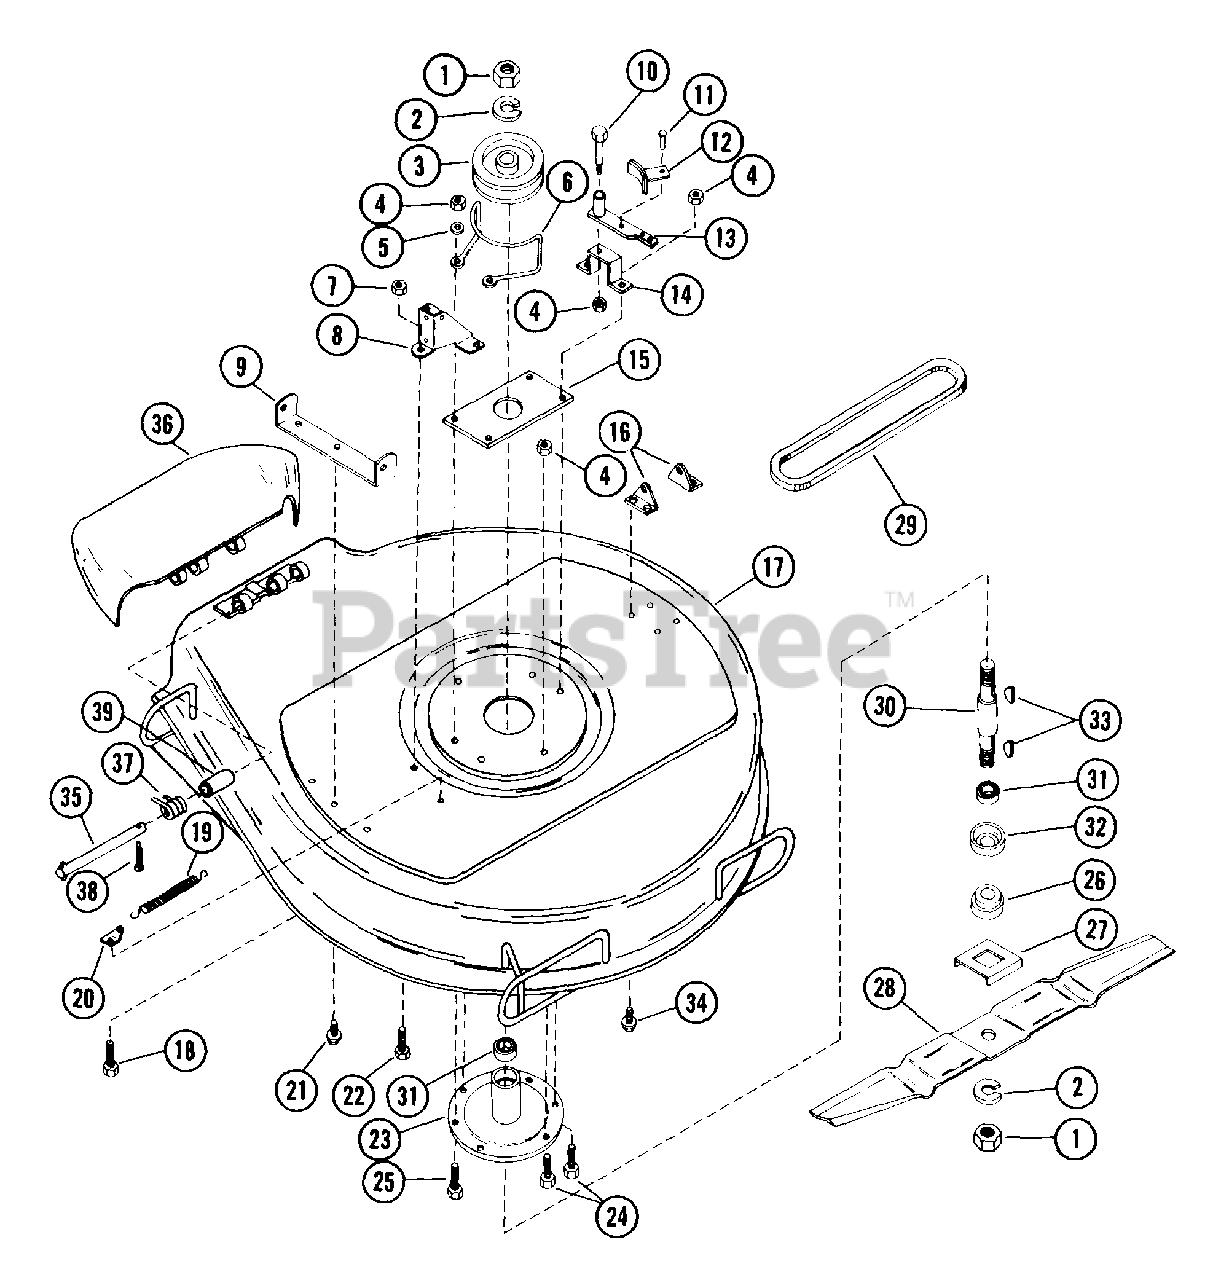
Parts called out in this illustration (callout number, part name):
1	NUT-JAM .75-10 PL
2	WSHR-LK .750X.188 MED PL
3	MOWER SHEAVE
4	NUT-LK-CTR .375-16 GR A PL
5	WSHR-FL-STL .38X.875X.083 PL
6	MOWER BELT FINGER
7	NUT-LK .312-18 GR A PL
8	ENGAGEMENT BRACE
9	FRONT MOUNTING BRACKET
10	SHOULDER BOLT .50 X 1.75
11	RVT .25X.50 RH ST
12	BLADE BRAKE
13	BLADE BRAKE ARM
14	BLADE BRAKE SUPPORT
16	REAR MOUNTING BRACKET
17	MOWER PAN
18	BLT-SERHFWH .25-20X.50 PL
19	SG-TENS .072X.51X5.31 WLD 25
20	BRAKE CLIP
21	BLT-SCRHFWH .38-16X.50 PL
22	BLT-HEX .31-18X.50 PL GR2
23	SPINDLE HOUSING
24	BLT-HEX .38-16X1.00 PL
25	BLT-HEX .38-16X1.25 PL GR 2
26	RETAINER HUB
27	BLADE TRAY
28	MOWER BLADE
29	V-BELT, 5L-RAW EDGE
30	MOWER SPINDLE
31	BRG-BALL .751X1.78X.61
32	BEARING SLINGER
33	KEY-WDRF .188X.875X.375 SAE11
34	BLT-SERHFWH .31-18X.50 PL
35	CLEVIS PIN
36	PAN CHUTE EXTENSION
37	SG-TORS .095X.50X 1.0
38	PIN-COTR .09X.75 PL
39	BSHG-SLV .334 X .502 X 1.437
